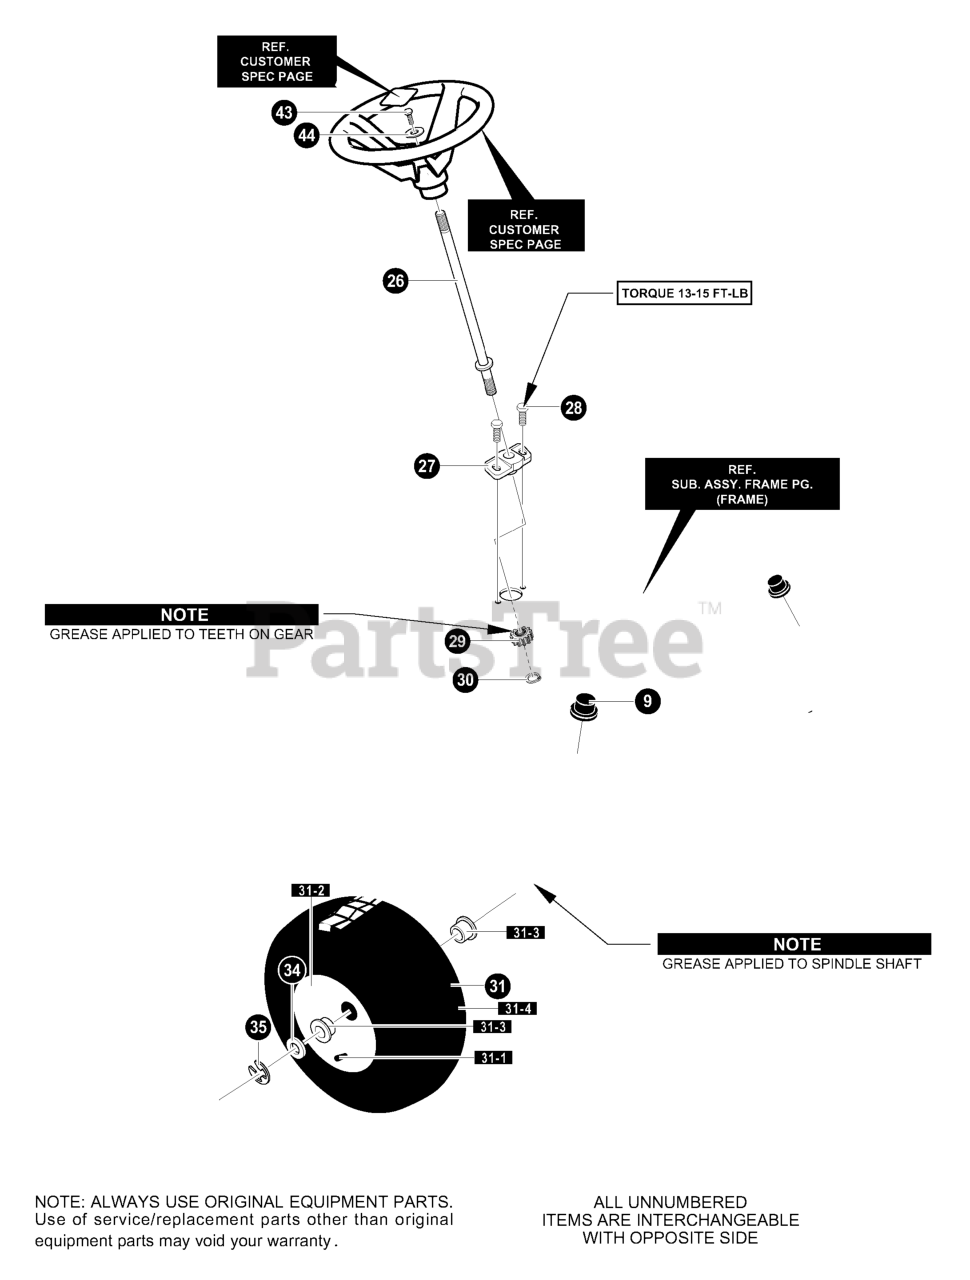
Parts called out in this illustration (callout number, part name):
9	DUST HUB CAP
26	SHAFT, STEERING
27	BEARING-LOWER
28	SCREW, 5/16-18 x 0.75
29	GEAR PINNION
30	RING, RET E.
31	TIRE & RIM, 15X6.0-6
31-1	VALVE STEM
31-3	BEARING
31-4	TIRE, 15X6X6
34	WASHER, FLAT .765 x 1.81 x .059
35	E-RING
43	SCREW, 1/4-20X.75 HHC
44	WASHER, FLAT .281X1.25X.06
